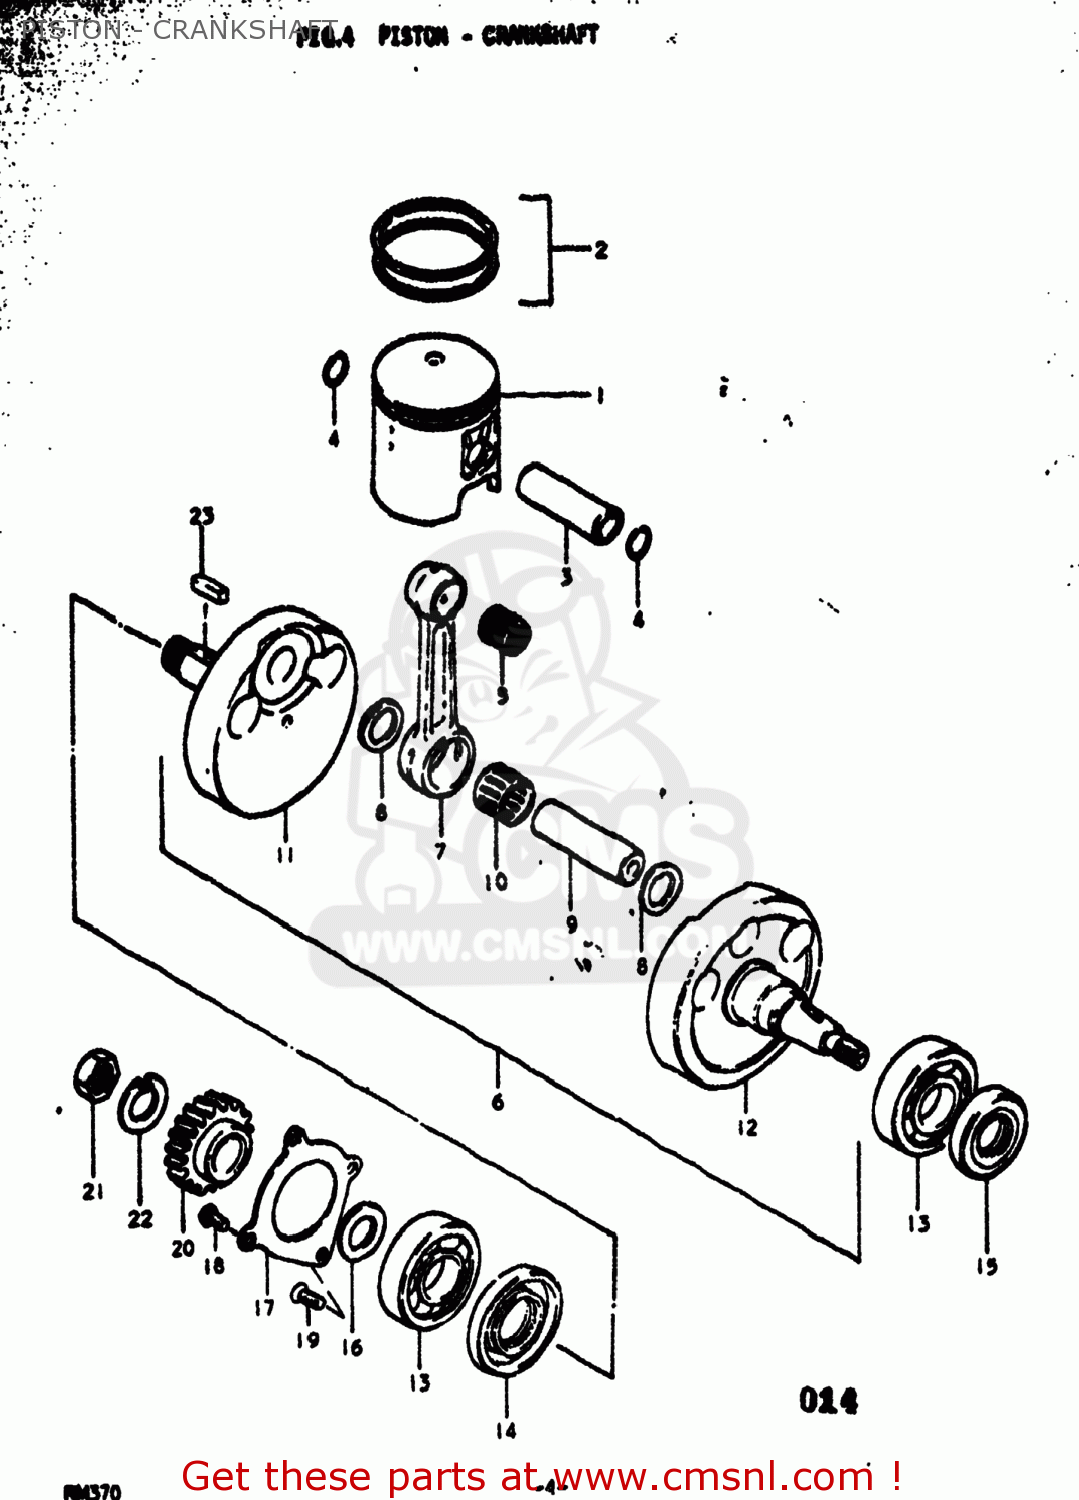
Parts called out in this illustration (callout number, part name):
1	PISTON
2	RING SET,PISTON
3	PIN,PISTON (18MM)
4	CIRCLIP
5	BEARING(18X23X22)
6	CRANKSHAFT ASSEMBLY
7	ROD,CONNECTING
8	WASHER(24X29X1.5)
9	PIN,CRANK
10	BEARING
11	CRANKSHAFT
12	CRANKSHAFT,LEFT
13	BEARING
14	SEAL,OIL(40X72X9)
15	SEAL,OIL(24X50X9)
16	WASHER
17	PLATE
18	SCREW
19	SCREW
20	GEAR,PRIMARY DRIVE
21	NUT
22	WASHER
23	KEY
